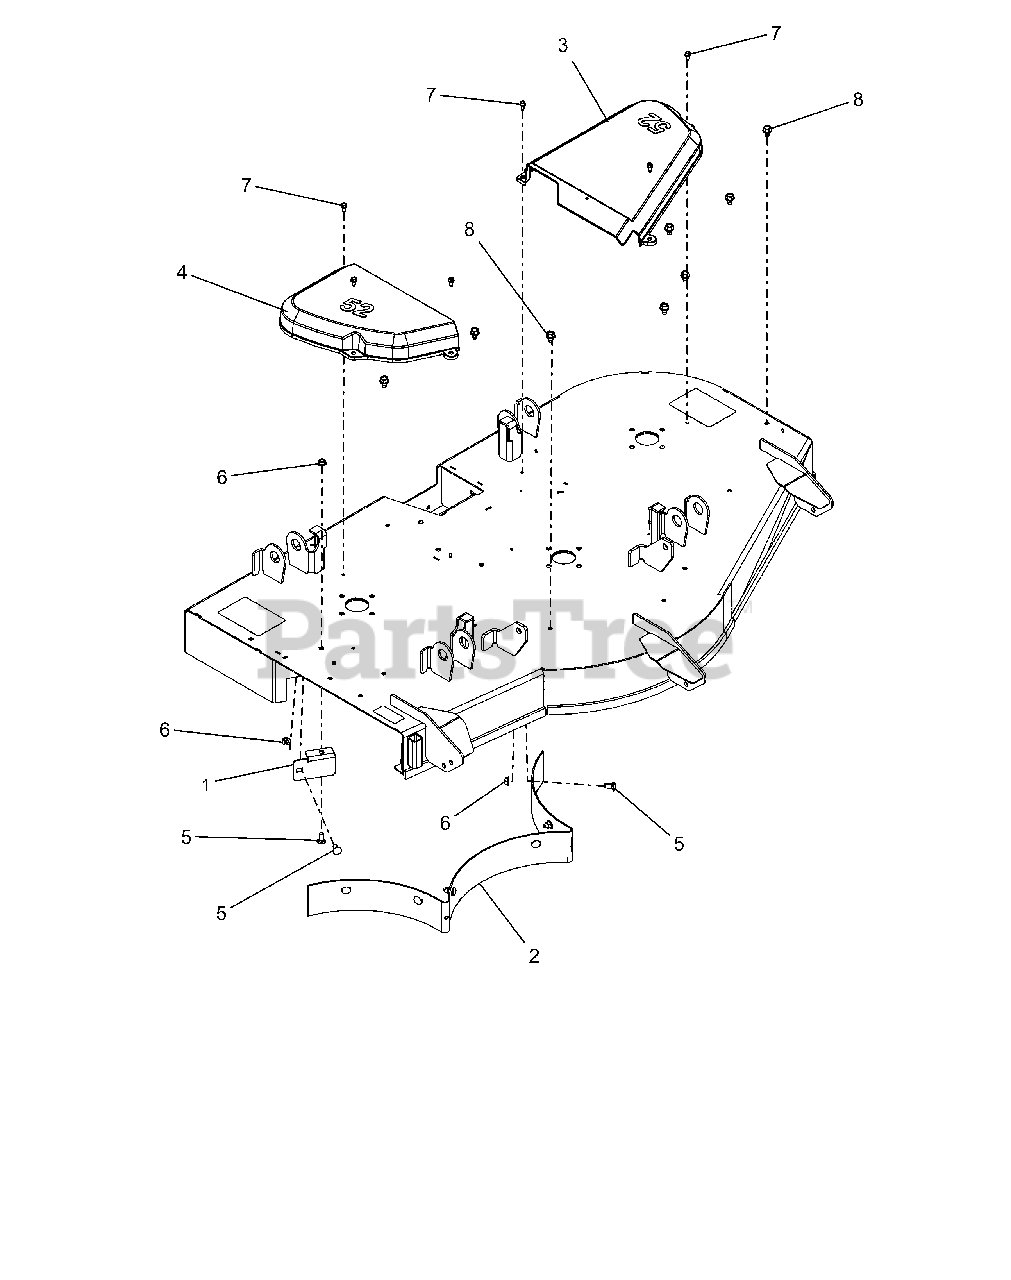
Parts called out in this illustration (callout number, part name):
1	STRIP, DEFLECTOR - 52"
2	BAFFLE, REAR - REMOVABLE 52"
3	COVER, BELT 52" LH
4	COVER, BELT 52" RIGHT
5	@BLT-RDHDSQNK .31-18X.75 G5YZ
6	@NUT-LK-TOP-FLG .31-18 YWZC
7	SCR-TAP .25-20X.50 HWH TR YWZ
8	@SCR-TAP .38-16X.50 HWH TR YWZ
